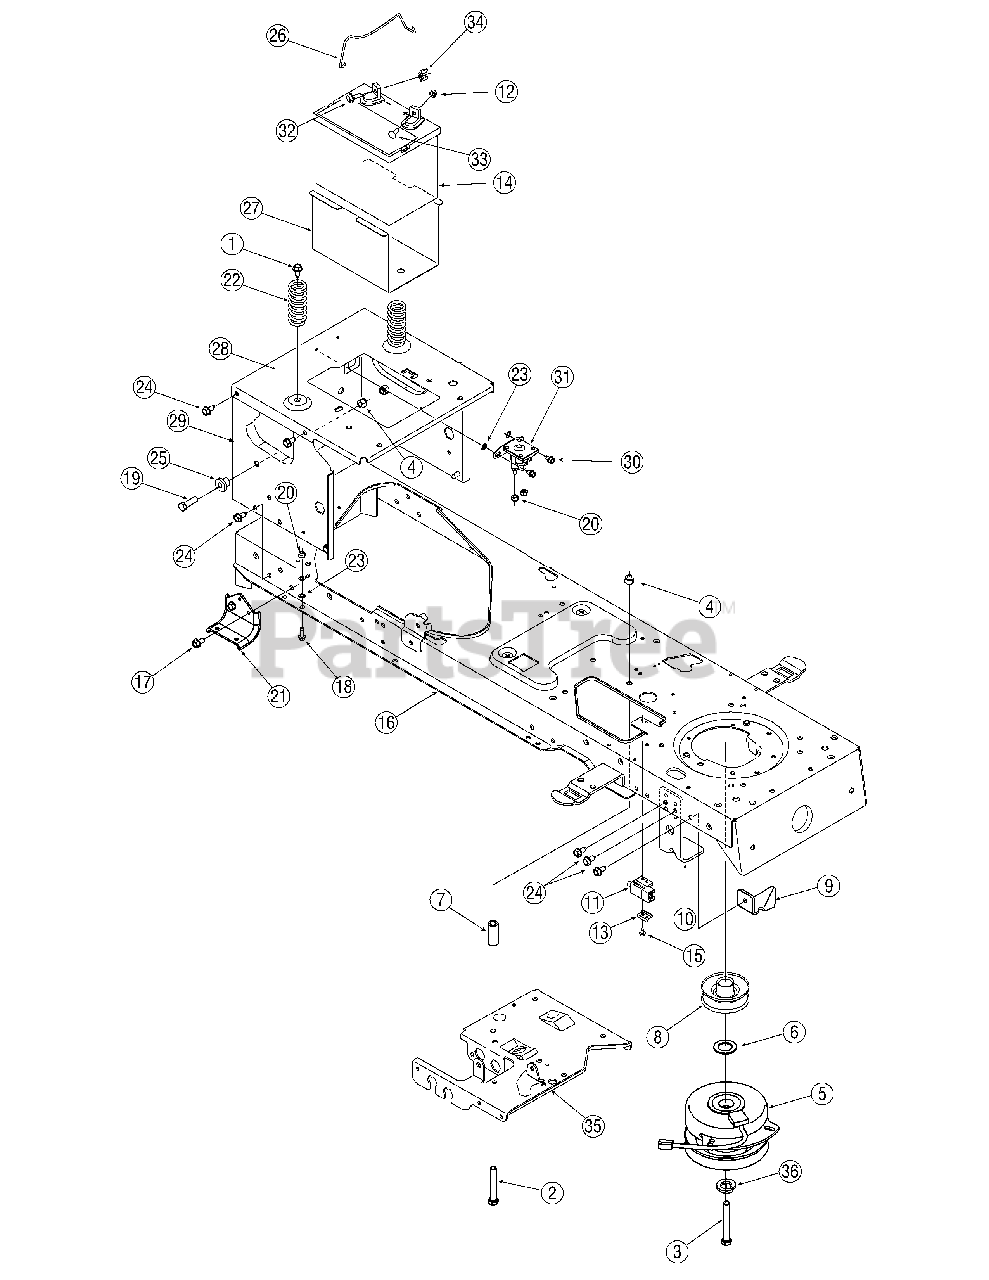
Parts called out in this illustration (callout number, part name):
1	Screw, 5/16-18 x 0.75
2	Screw, 3/8-16, 2.50, Gr5
3	Screw, 7/16-20, 3.50, Gr5, Lock
4	Nut, Flange Lock, 3/8-16, GrF, Nylon
5	PTO Clutch, Electric
6	Washer, Flat, 1.031 x 1.620 x.095
7	Spacer,.385 ID x.635 OD x 1.54
8	Pulley, Engine, 3.56 Diameter
11	Switch
12	Nut, Sems, 1/4-20
13	Switch Plate
14	Battery, 235 CCA
15	AB Screw, #10-16 x.500
18	Screw, 1/4-20, 0.750
19	Screw, 3/8-16, 1.25, Gr5
20	Nut, Flange Lock, 1/4-20, GrF, Nylon
22	Spring, Compression, 1.28 OD x 3.125
23	Washer, Lock, 1/4, External
24	Screw, 5/16-12, 0.75
25	Spacer, Shoulder,.38 x 1.0 x.70
26	Hold Rod, Battery
31	Solenoid, 12V, 100 Amp
32	Screw, Shoulder,.250 x.15, 1/4-20
33	Screw, Carriage, 1/4-20,.75
34	Nut, Wing, 1/4-20
36	Lock Washer, 7/16
